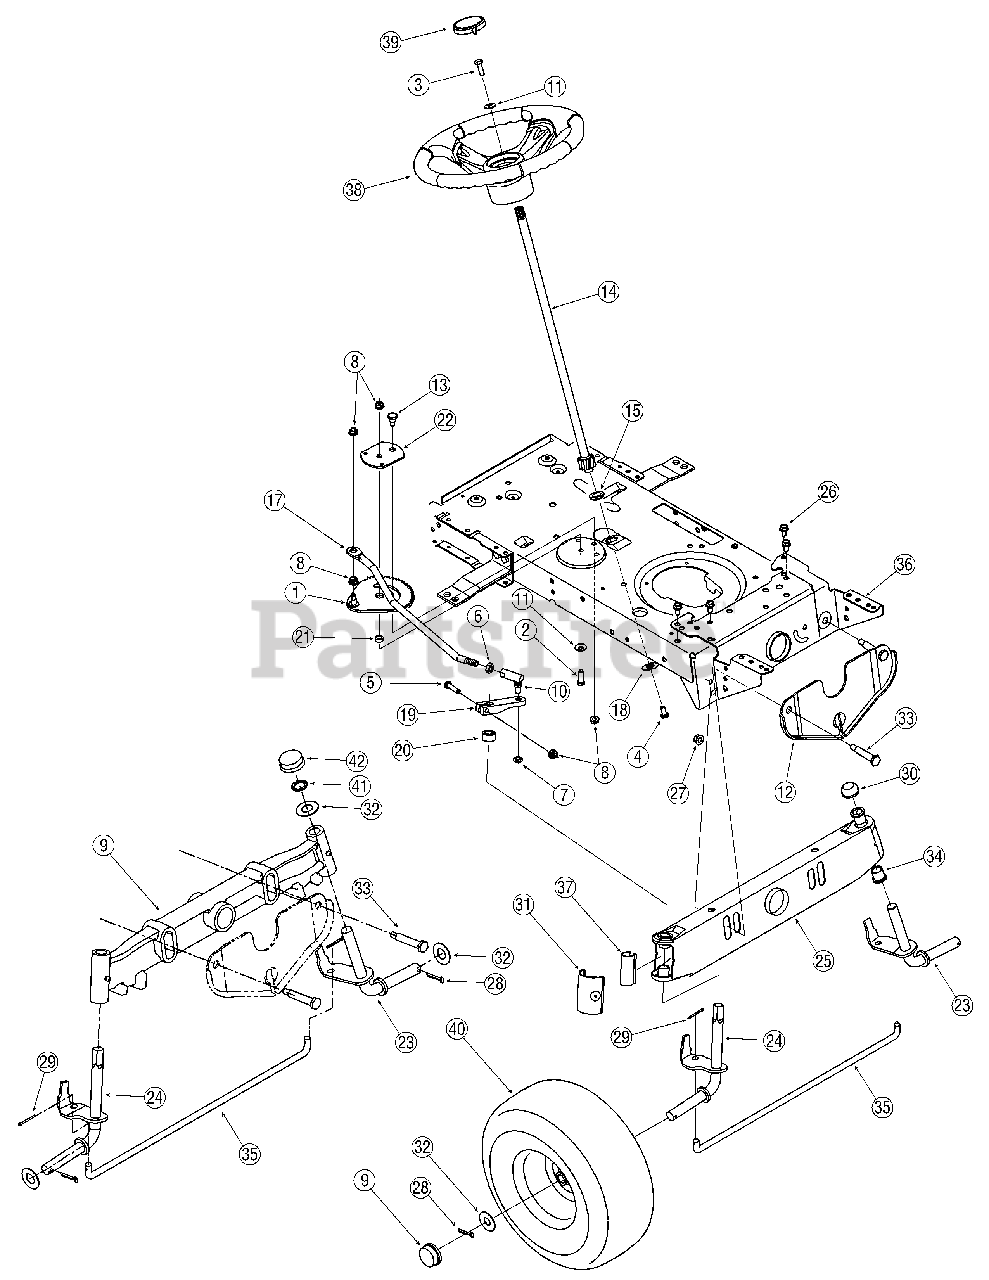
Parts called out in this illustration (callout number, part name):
1	Gear Assembly, Steering
2	Screw, 5/16-18, 1.00, Gr5
3	Screw, 5/16-18, 1.00, Gr5, Lock
4	Screw, Mach, 5/16-18, 0.750
5	Screw, 5/16-18, 1.75, Gr5
6	Nut, Jam, 7/16-20, Gr2
7	Nut, Jam Lock, 3/8-24, Gr2
8	Nut, Flange Lock, 5/16-18, Grf, Nylon
9	Hub Cap
10	Ball Joint, 7/16-20, Lock
11	Washer, Bell, .340 x .872 x .060
13	Screw, Shoulder, .435 x .3485, 5/16-18
14	Steering Shaft, 5/8 Spline x 21.86
15	Bearing, Flange, Hex 5/8
16	Plastic Bushing .380 ID
17	Drag Link, Steering
18	Cap, 1.25 x .16
20	Spacer, .710 ID x .125 OD x .56
21	Spacer, .322 ID x .625 OD x .21
22	Stabilizer Plate, Gear Segment
26	Screw, 5/16-12, 0.750
27	Nut, Flange Lock, 3/8-16, GrF, Nylon
28	Pin, Cotter, 5/32, 1.25
29	Pin, Cotter, 1/8 x 1.25
30	Push Cap, 3/4
31	End Cap, Pivot Bar (w/ Fitting)
32	Washer, Flat, .78 x 1.59 x .060
33	Screw, Shoulder, .500 x 2.380, 3/8-16
34	Bearing, Flange, .760 x .941 x 1.0
35	Tie Rod
37	Axle End Cap, Standard
38	Steering Wheel, Standard Grip
38	Steering Wheel, Soft Grip
39	Cap, Steering Wheel (no logo)
39	Cap, Steering Wheel (sprig logo)
39	Cap, Steering Wheel (tine logo)
41	Push Nut (Optional)
42	Hub Cap (Optional)
43	Pivot Axle (Optional)
